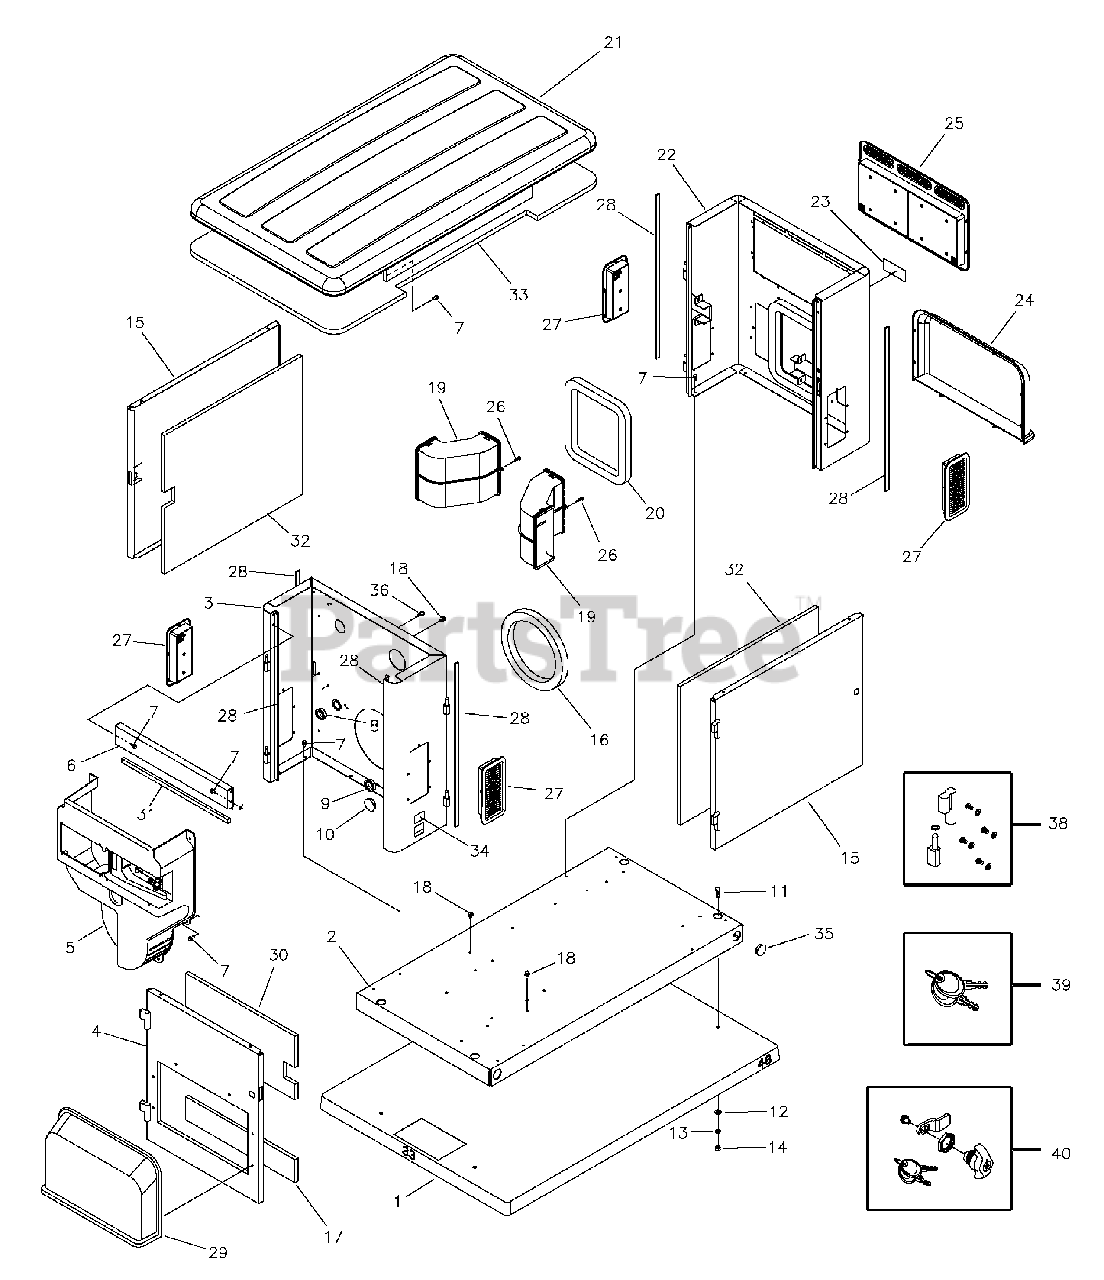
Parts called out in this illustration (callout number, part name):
1	PAD, Mounting w/ Holes
2	BASE, Mounting
3	BULKHEAD, Engine
4	ASSEMBLY, Door, Engine End
7	BOLT
9	BUSHING, Snap, 1-1/2
11	*CAPSCREW, Hex Head, 3/8-16 x 1
12	*WASHER, Flat, 3/8-M10
13	*WASHER, Lock, 3/8
14	*NUT, 3/8-16
16	SEAL, Foam
17	INSULATION, Engine Door, Bottom
18	MOUNT, Tie Wrap
22	BULKHEAD, Alternator
24	COVER, Air Intake
25	ASSEMBLY, Vent, Exhaust
29	COVER, Air Intake, Engine
30	INSULATION, Engine Door, Top
34	DECAL
